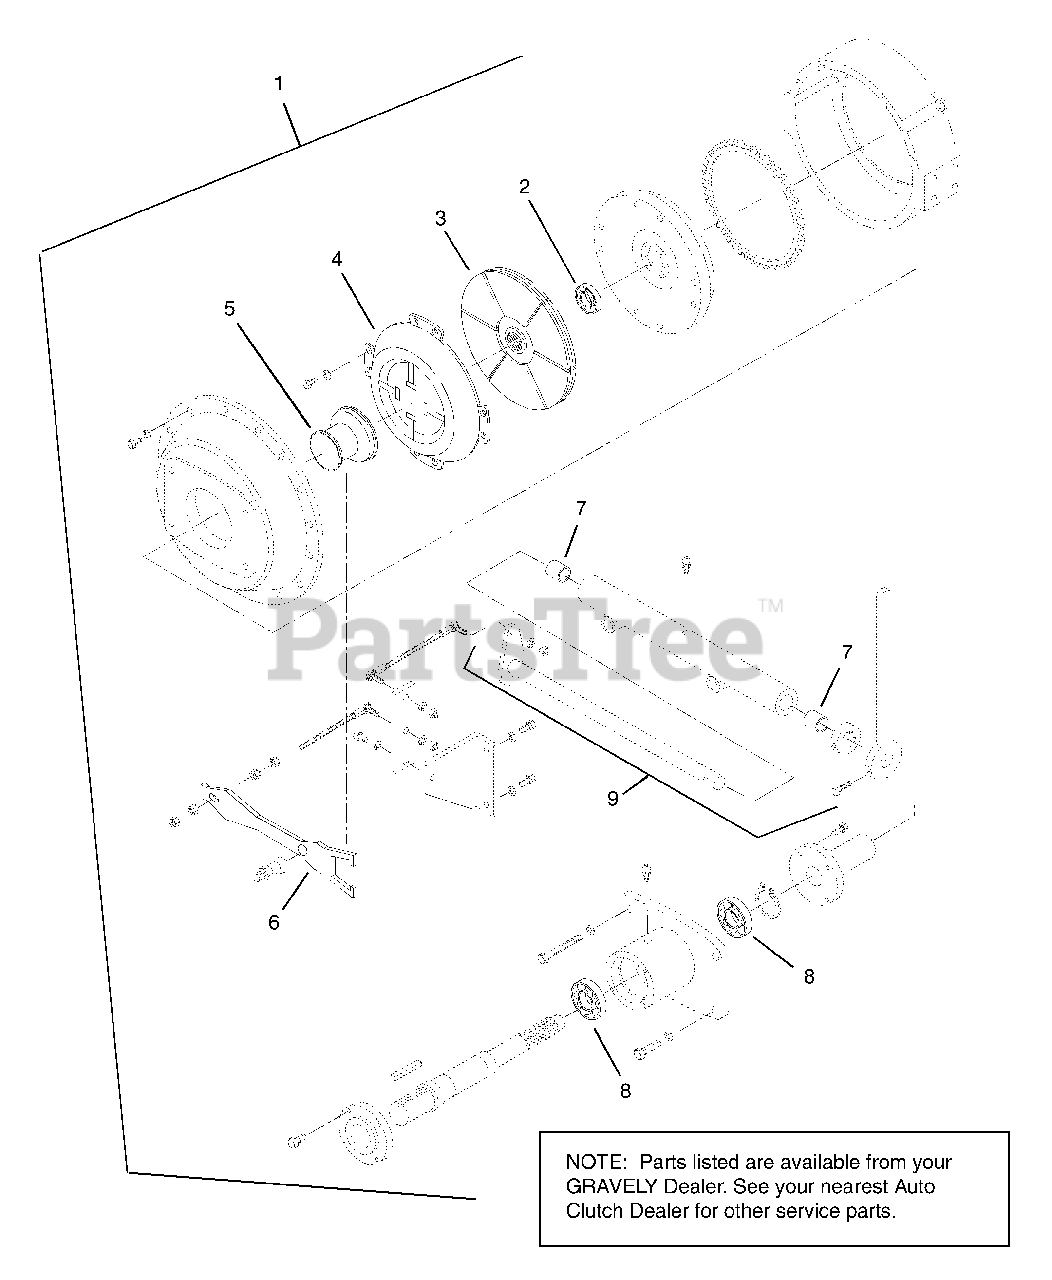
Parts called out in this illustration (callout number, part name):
1	Clutch Assembly
2	Pilot Bearing
3	Disk, Clutch
4	Plate, Pressure Clutch
5	Bearing, Throw-Out
7	Bushing, Shaft
8	Bearing, PTO
9	Shaft - Clutch Release Assembly
